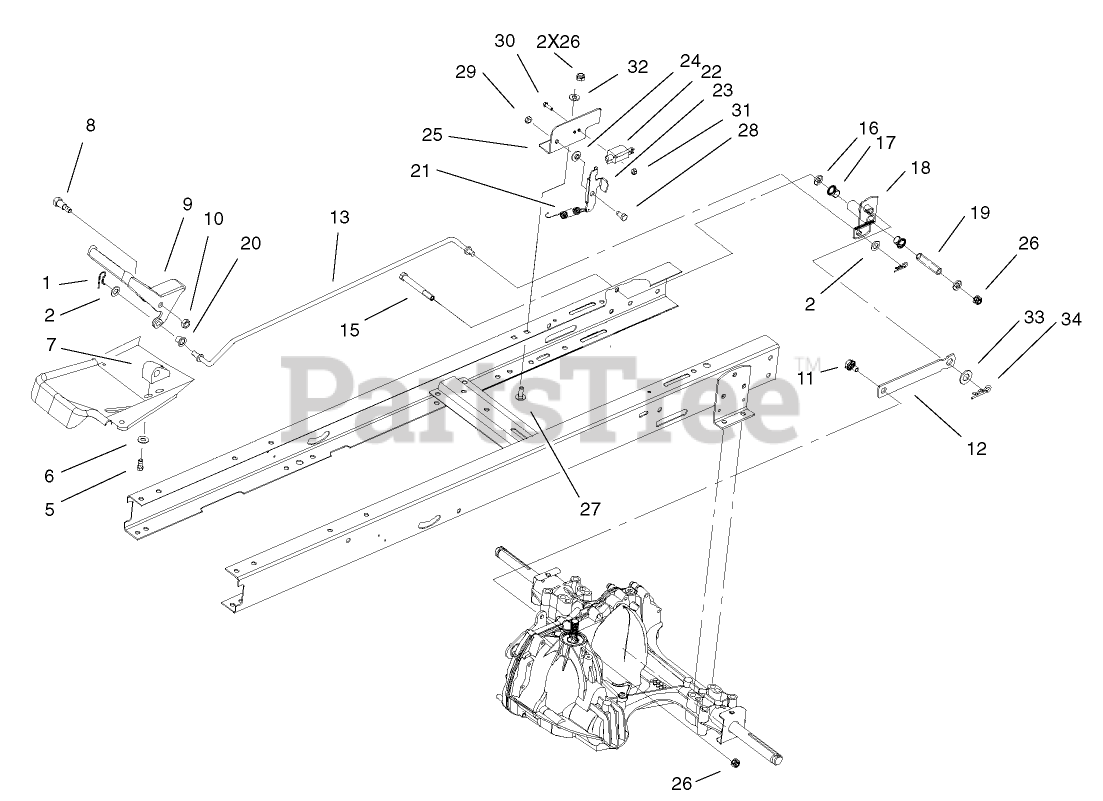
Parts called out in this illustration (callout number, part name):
2	WASHER-FLAT
5	SCREW-PLASTITE
6	WASHER-FLAT
7	BLOCK-PIVOT
8	SCREW-SHOULDER, HH
9	PEDAL-CONTROL, SPEED
11	BOLT-SHOULDER
12	LINK-CONTROL, SPEED
13	ROD-CONTROL, SPEED
15	SCREW-HH
16	WASHER-FLAT
17	BUSHING-NYLINER
18	PIVOT ASM
19	SPACER-PIVOT
20	BUSHING-FLANGED
21	SPRING-EXTENSION
22	SWITCH-POLE, SINGLE
23	BRACKET-PIVOT
24	WASHER-STEPPED
25	BRACKET-ADJUSTMENT
26	NUT-LOCK, NI
27	SCREW-CARR
28	SCREW-HHF
29	NUT-LOCK, NI
30	SCREW-SHH
31	NUT-LOCK
32	WASHER-PLAIN
33	WASHER-FLAT
34	PIN-HAIR
